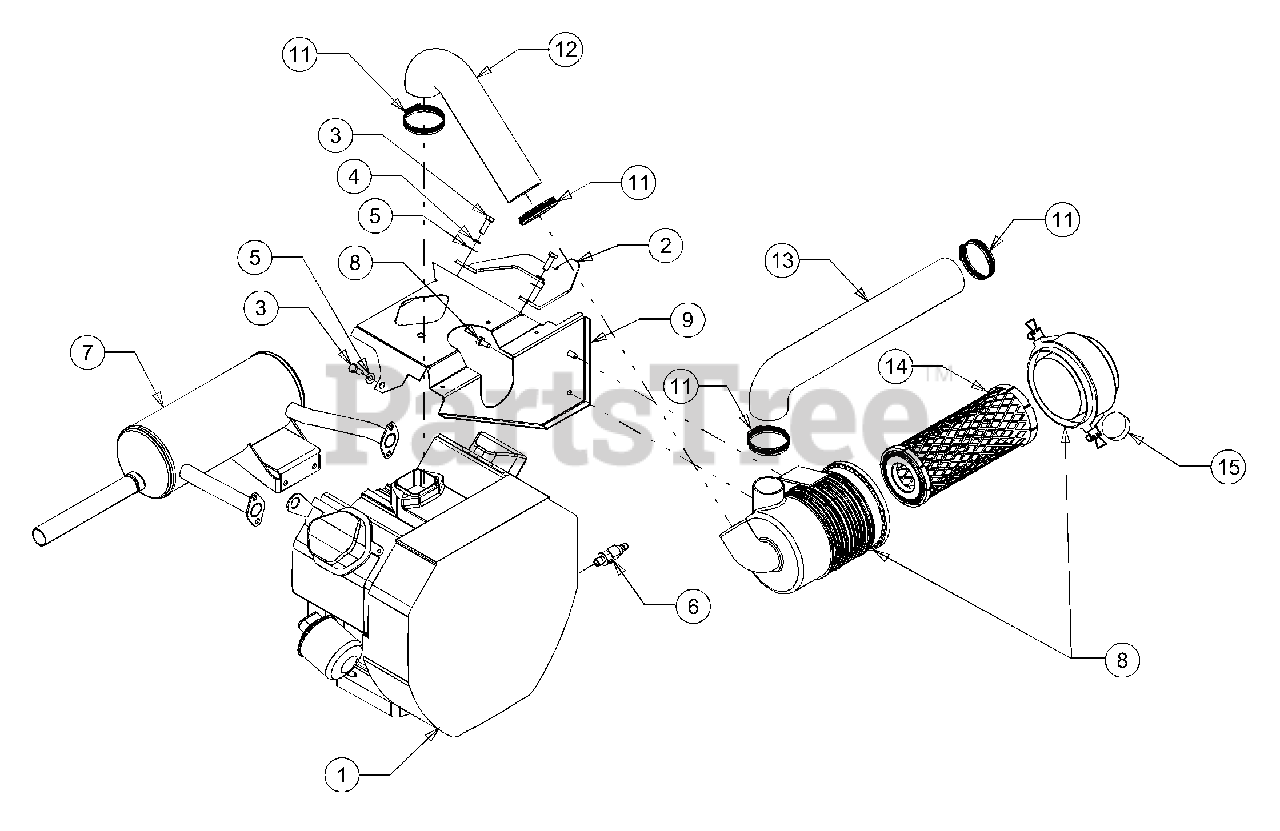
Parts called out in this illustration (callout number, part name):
1	Engine,Honda GX620K1
2	Support, Upper Transmission
3	Hex Screw, M8-1.25 x 25, Gr8
4	Washer, Lock, 5/16
5	Washer, Flat, .33 x .678 x .030
6	Valve, Oil Drain
7	Muffler,Honda GX620
8	Filter Assembly, Air Cleaner
11	Hose Clamp, Adjustable 2"-3"
12	Hose, Air Filter,Honda
13	Hose, Air Cleaner Intake
14	Filter, Air Cleaner Element
15	Filter, Air Cleaner Dust Valve
